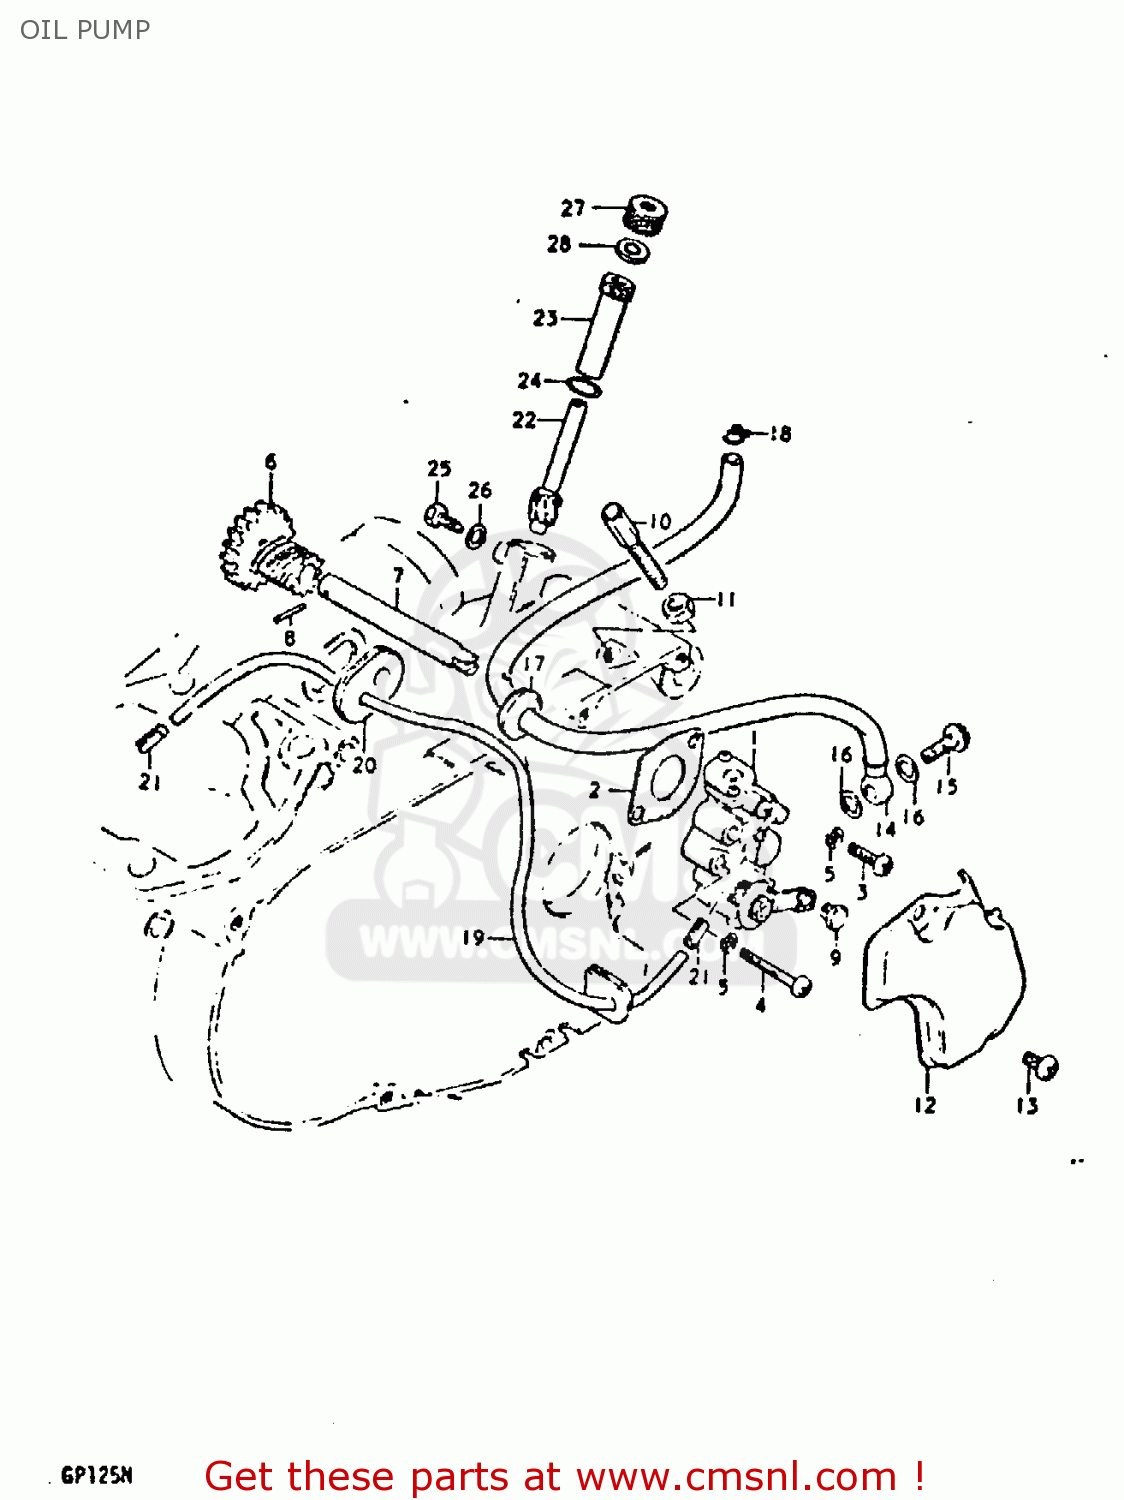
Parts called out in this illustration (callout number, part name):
1	PUMP ASSY, OIL
2	GASKET,OIL PUMP (NAS)
3	SCREW
4	SCREW
5	LOCK WASHER
6	GEAR,OIL PUMP DRIVE
7	SHAFT,OIL PUMP DRIVE GEAR
8	PIN(2.5X19.8)
9	TERMINAL,CABLE
10	BOLT
11	NUT
12	CAP,OIL PUMP INSPECTION
13	SCREW
14	HOSE,OIL NO.1
15	UNION BOLT
16	GASKET(6.2X11X1).2 (NAS)
17	GROMMET
18	CLIP
19	HOSE,OIL NO.2
20	GROMMET,OIL HOSE NO.3
21	CLIP
22	GEAR, TACHO. DRIVEN (NT:10)
23	SLEEVE,TACHOMETER DRIVE GEAR
24	O RING(D:1.3,ID:9.6)
25	BOLT
26	WASHER
